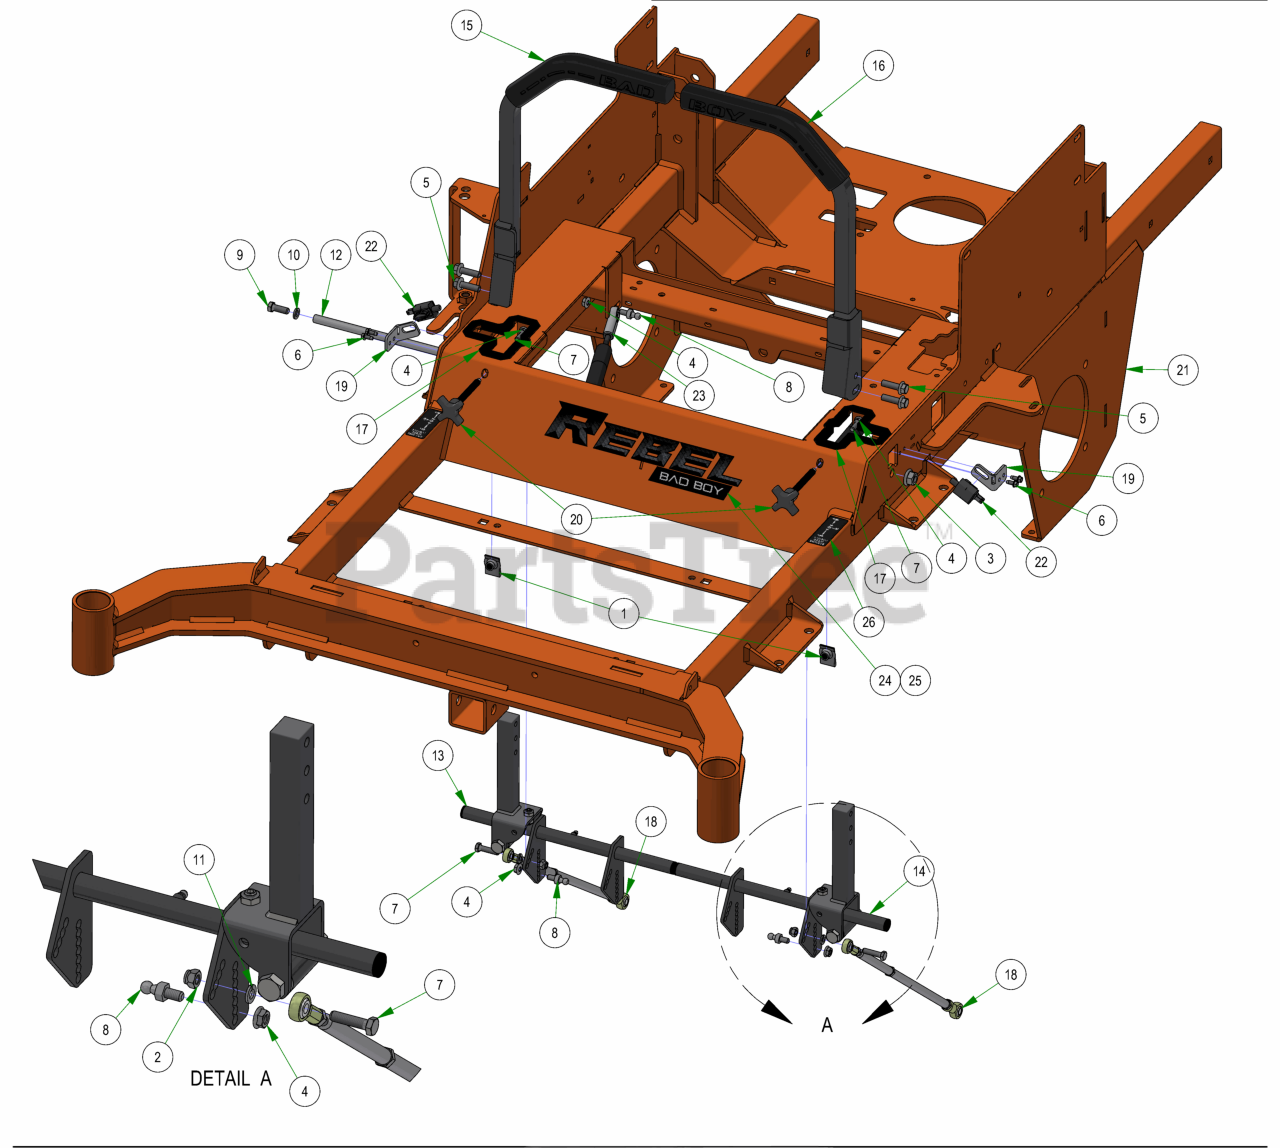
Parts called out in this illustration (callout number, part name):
1	Extruded Nut 3/8"-16 3/4" Hole Center With Patch
2	5/16-18 NYL INS L/N ZC
3	1/2-13 NYLON INSERT FLANGE LOCKNUT ZINC
4	5/16-18 HEX SERRATED FLANGE NUT HARD/ZINC
5	3/8-16 X 1 1/4 HEX WASHER UNSLOT MACHINE SCREW ZINC GR5
6	12-24 X 1/2 HEX WASHER UNLSOT F TCS ZINC
7	5/16-18 X 1-1/4 HEX C/S (GR.5) ZC
8	10mm Damper Ball Stud-Steering
9	3/8-16 X 1 GR 5 Hex Bolts Zinc
10	3/8 SPLIT LOCKWASHER ZINC
11	5/16 SPLIT LOCKWASHER ZINC
12	2019 Steering Actuator Rod
13	R Series Square Drive Arm Actuator RH Assembly
14	R Series Square Drive Arm Actuator LH Assembly
15	R Series Square Drive Arm RH Assembly
16	R Series Square Drive Arm LH Assembly
17	Snap-in Drive Arm Bushing
18	2024 Rebel Push Rod Assembly
19	Push In Arm Safety Switch R Series Bracket
20	Speed Limiting Knob 3/8-16X 3"
21	2023 Rebel Frame - Painted
22	Rail Mount Safety Switch
23	Steering Damper
24	Rebel back Plate & Front Decal
25	Rebel X back Plate & Front Decal
26	2018 LH/RH Steering Control Decal Roll
